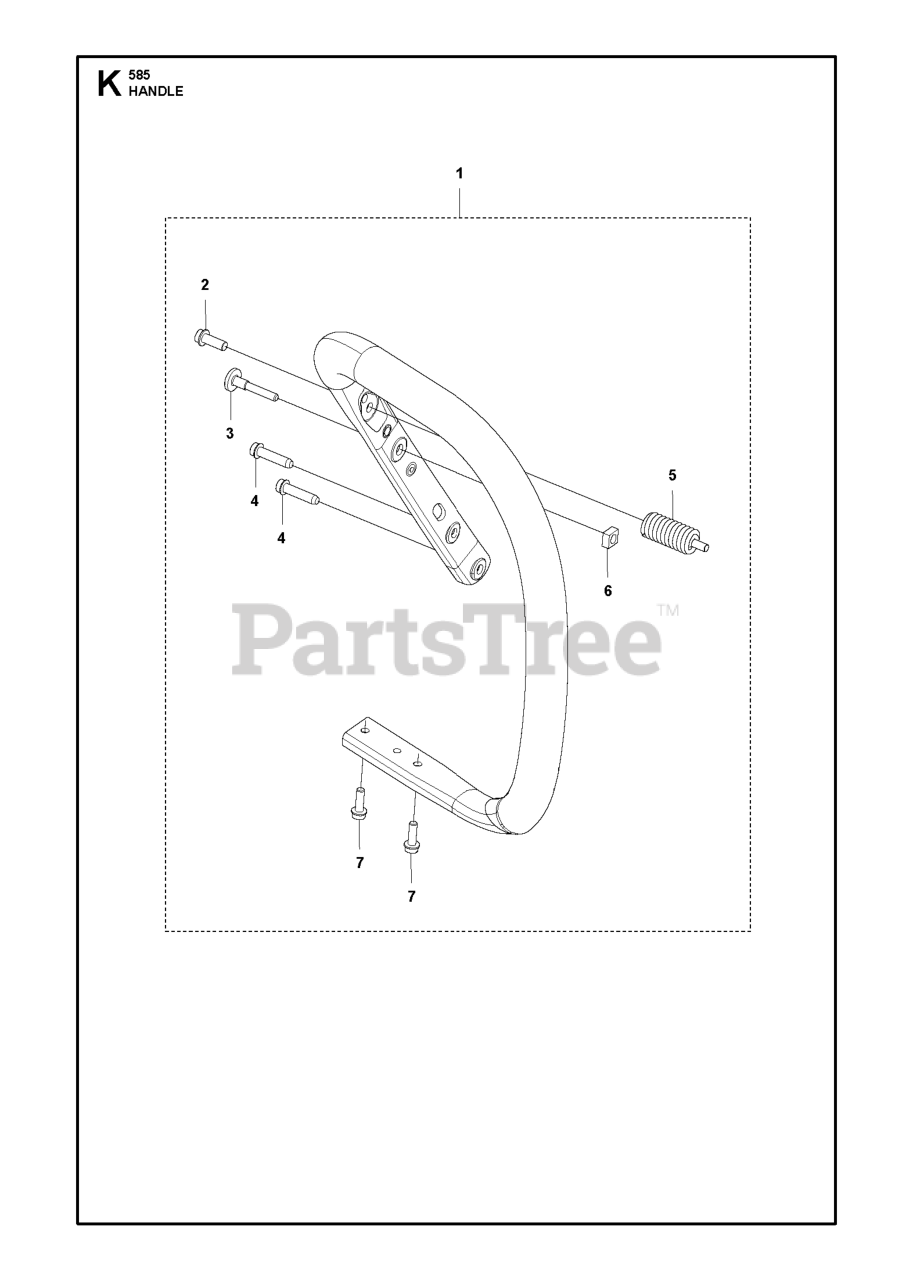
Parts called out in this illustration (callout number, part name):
1	HANDLE SYSTEM
2	SCREW ITXSCFM
3	SCREW ITXPANM MOVEMENT LIMITER
5	ANTIVIBRATION ELEMENT CYLINDE
